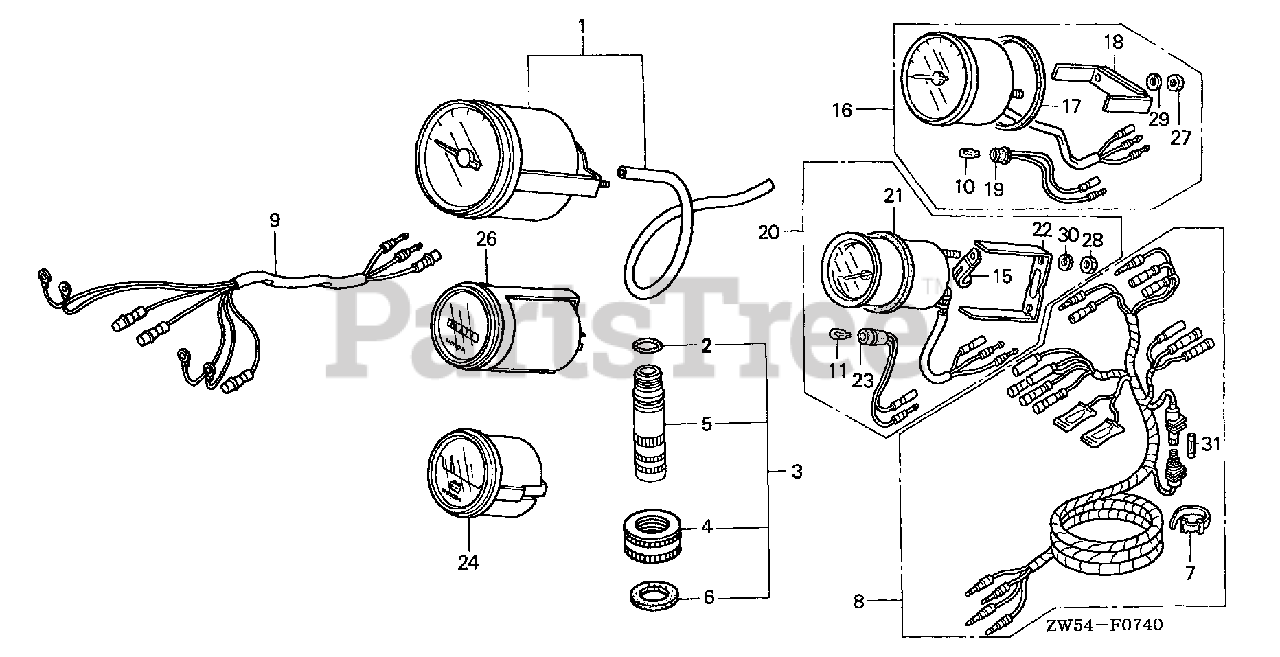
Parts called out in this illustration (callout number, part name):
1	SPEEDOMETER KIT
2	O-RING (11.8X2.4)
3	JOINT ASSY., HOSE
4	NUT, WATER MOUTH
5	JOINT ASSY., HOSE
6	SEAT, WATER MOUTH
7	BAND B1, WIRE
8	HARNESS ASSY., METER (A)
9	HARNESS ASSY., METER (B)
10	BULB, WEDGE BASE (T10)
11	BULB, WEDGE BASE (12V 1.7W)
16	TACHOMETER ASSY.
20	METER ASSY., TRIM
24	METER ASSY., VOLT
26	METER ASSY., HOUR L.C.D.
27	NUT, HEX. (5MM)
28	NUT, HEX. (4MM)
29	WASHER, SPRING (5MM)
30	WASHER, SPRING (4MM)
31	FUSE A (10A)
